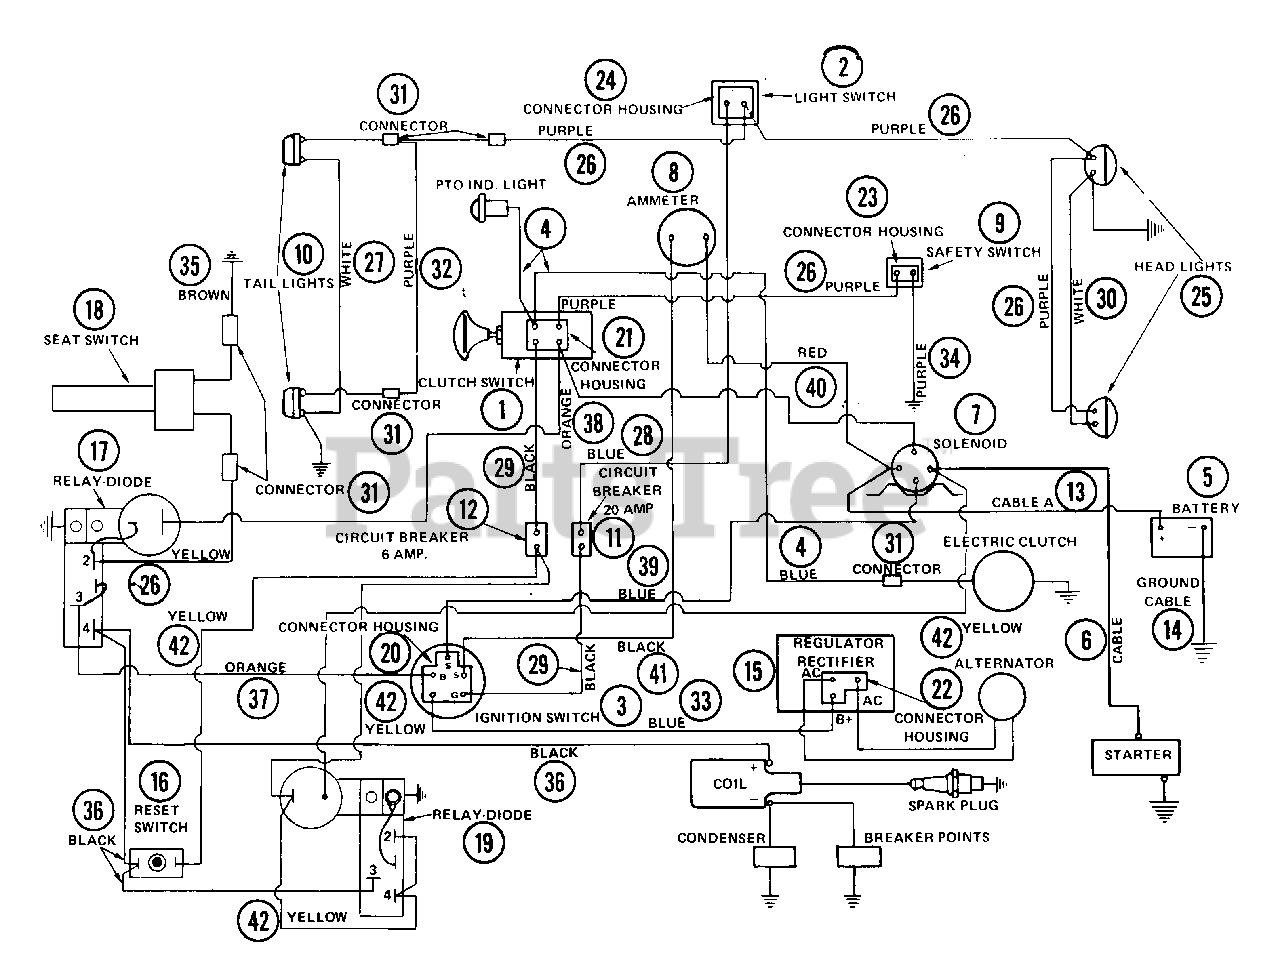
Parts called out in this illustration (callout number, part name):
1	CLUTCH SWITCH
2	LIGHT SWITCH
3	IGNITION SWITCH
4	P.T.O. INDICATOR & WIRE
5	BATTERY
6	GROUND CABLE .31X22.00X.31
7	SOLENOID
8	AMMETER
9	SWITCH-NEUTRAL START N.O.
10	TAIL LIGHT
11	CIRCUIT BREAKER
12	CIRCUIT BREAKER
14	GROUND CABLE
15	REGULATOR RECTIFIER
17	RELAY - DIODE
18	SWITCH SEAT
19	CLUTCH CONTROL RELAY
20	CONNECTOR HOUSING
21	CONNECTOR
22	CONNECTOR
23	CONNECTOR
24	CONNECTOR
25	HEAD LIGHT
26	WIRE HARNESS
27	WIRE
27	GROUND FOR TAIL LITES
28	WIRE
28	BRAKE TO LITE SWITCH
29	WIRE
30	WIRE
31	WIRE CONNECTOR
32	WIRE
33	WIRE
34	WIRE
35	WIRE GROUND
36	WIRE
36	6A C.B. AND COIL
37	WIRE
38	WIRE
39	WIRE
40	WIRE
41	WIRE
42	RELAY WIRE
